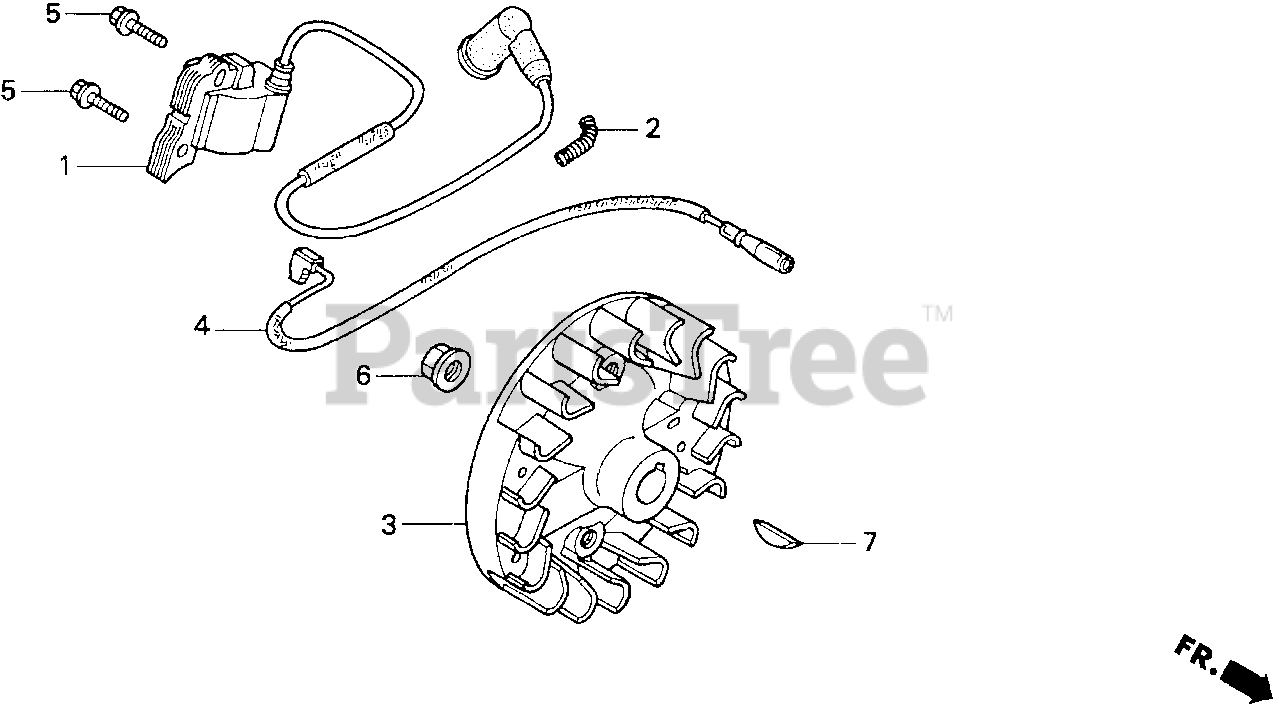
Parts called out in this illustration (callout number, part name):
1	COIL ASSY., IGNITION
2	TUBE A, CORRUGATED (7X18)
3	FLYWHEEL COMP.
4	WIRE, STOP SWITCH
5	BOLT-WASHER (5X16)
6	NUT, FLANGE (8MM)
6	NUT, FLANGE (10MM)
7	KEY, WOODRUFF (16X12)
